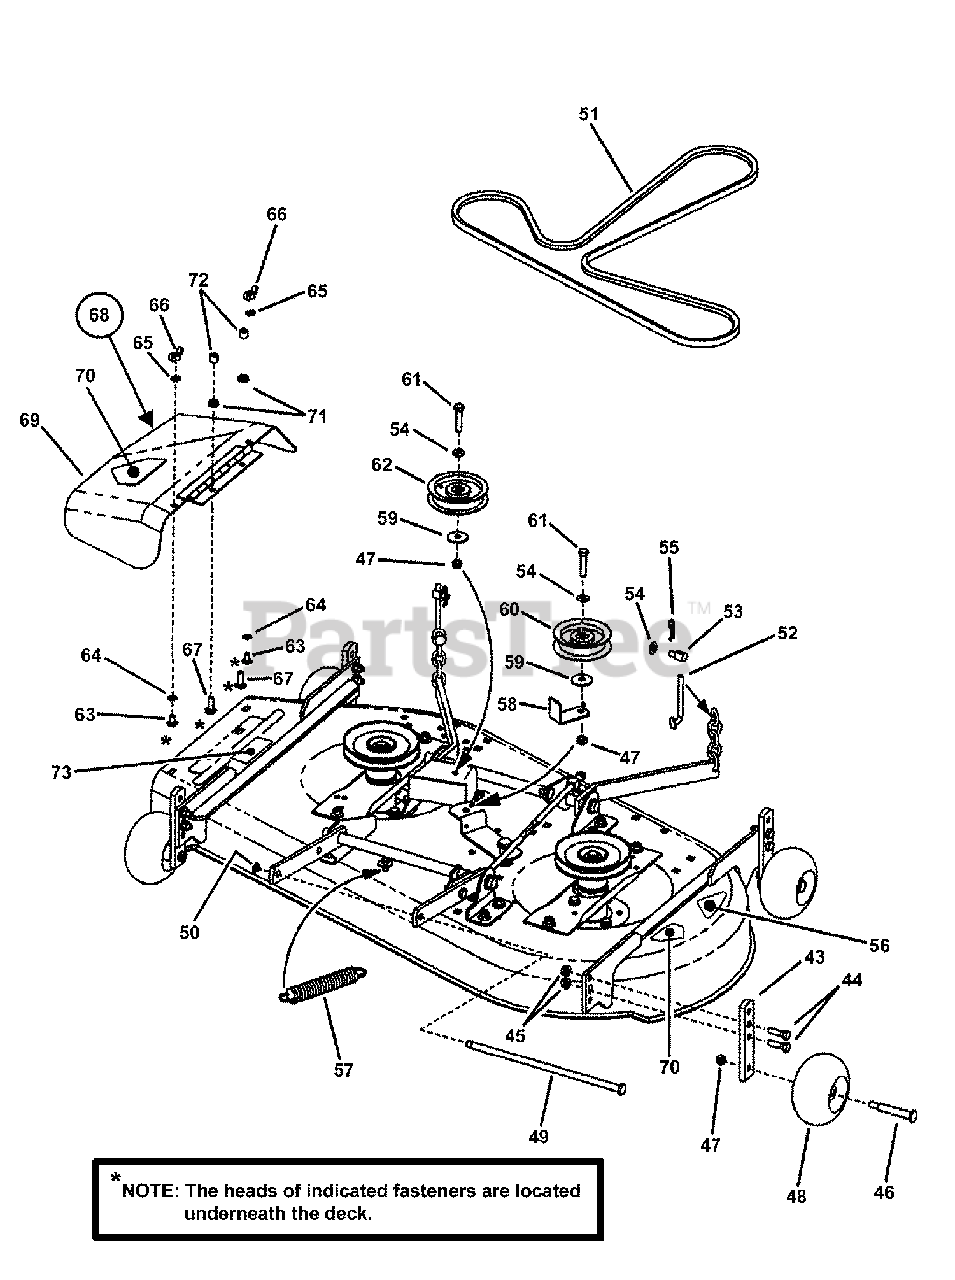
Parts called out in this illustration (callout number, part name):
43	POST, Anti-Scalp
44	SCREW, 3/8-16 x 1-1/4 Hex Head Cap, GR5
45	NUT, 3/8-16 Hex Flange Lock
46	BOLT, 3/8-16 x 2-5/8" Shoulder
47	NUT, 3/8-16 Hex Center Lock, GR5 or B
48	WHEEL, Gage
49	ROD, Deck Support
50	RING, .438 External Retaining
51	BELT, HA Section, (94.5" nom. effective length)
52	ADJUSTER, Chain (5/16-18 thread)
53	SWIVEL, Adjustment
54	WASHER, 3/8" SAE Flat
55	HAIR PIN, 3/32 x 1-1/2"
56	DECAL, 42 Inch
57	SPRING, Extension 1.03 Dia. X 6.8" long
58	BELT GUIDE, 38/42 Idler
59	WASHER, Cone
60	IDLER, Flat (4.00 O.D.)
61	SCREW, 3/8-16 x 1-3/4" Hex Head Cap, GR5
62	IDLER, 4.12" Outside Diameter, Flat
63	BOLT, 5/16-18 x 5/8" Short Neck Carriage, GR5
64	RETAINER, 5/16" Bolt
65	WASHER, .32 x .58 x .08 Split Lock
66	WING LOCKNUT, 5/16-18
67	BOLT, 5/16-18 x 1" Short Neck Carriage, GR5
68	ASSEMBLY, Chute & Decal
69	WELDMENT, Side Chute
70	DECAL, Danger, Cut Finger (CPSC)
71	NUT, 5/16-18 Hex Flange Lock, GR5
72	CAP, Vinyl
73	DECAL, Chute/Deflector
